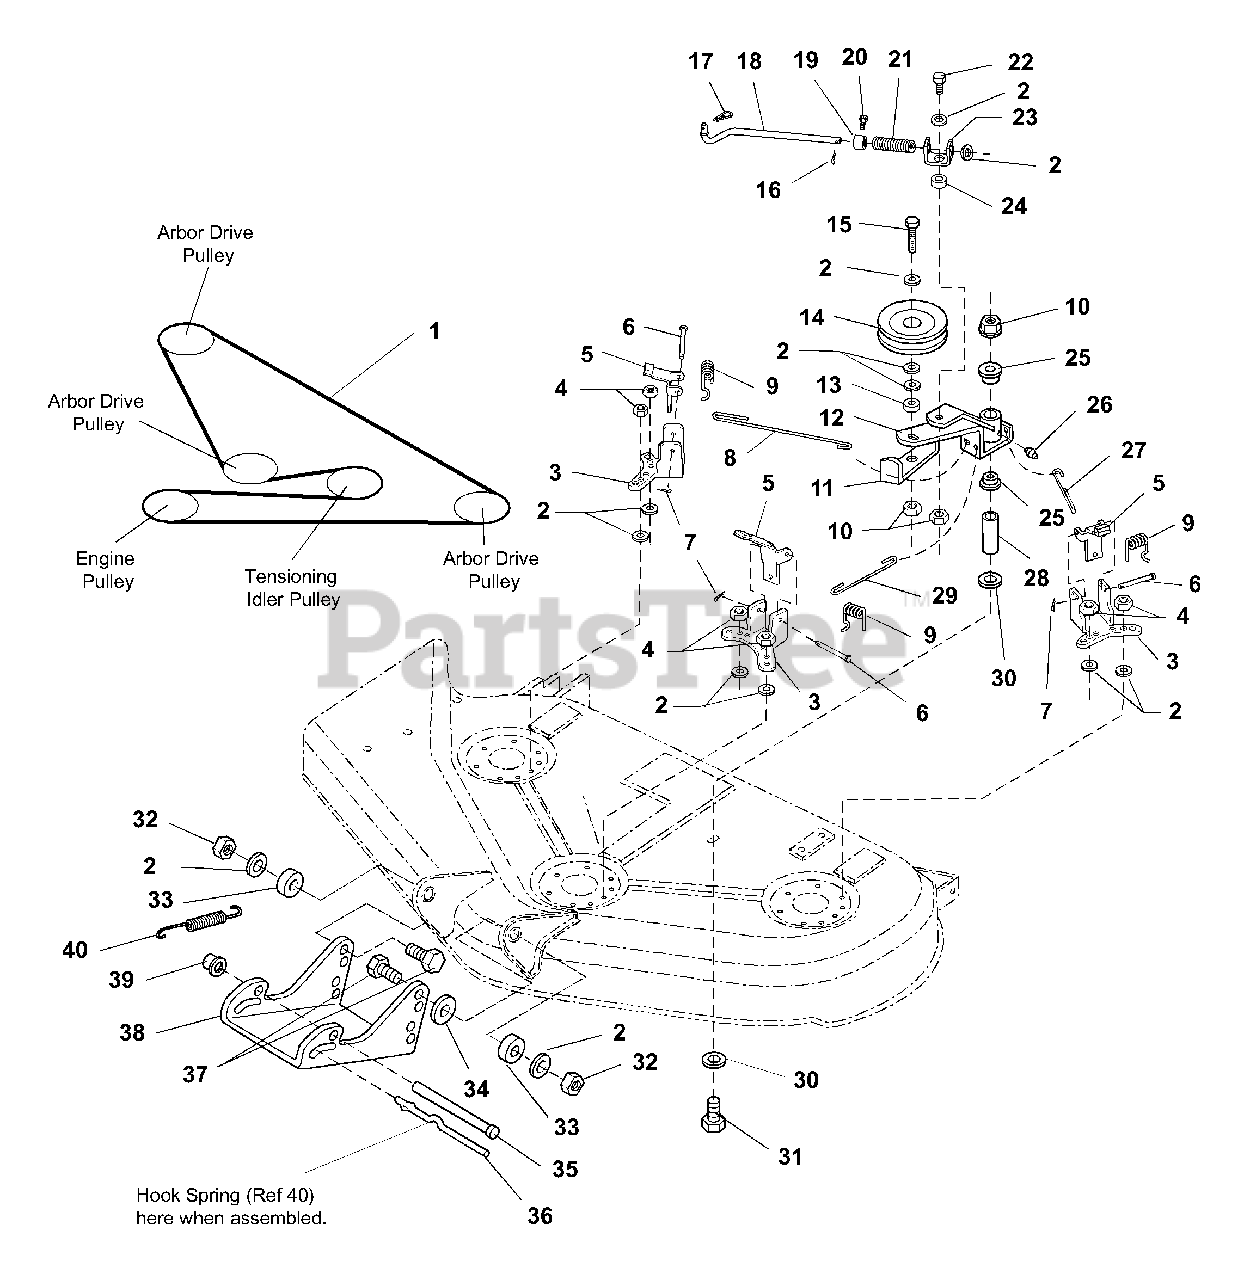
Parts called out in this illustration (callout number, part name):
2	WASHER, 3/8
3	SUPPORT, Brake Actuator
4	NUT, Hex Flange Whix Lock, 5/16
5	ACTUATOR & PAD ASSEMBLY, Brake
6	PIN, Clevis, 3/4 Hd
7	COTTER PIN
8	ROD, Brake R.H.
10	NUT, Hex Flange Whix Lock, 3/8
11	RETAINER, Belt
12	IDLER ARM ASSEMBLY, with Bushings
14	PULLEY ASSEMBLY, Idler
15	CAPSCREW, Hex Hd, 3/8-16 x 2
17	CLIP, Hair Pin
18	ROD, 2 Bends
19	COLLAR, Set
20	SET SCREW, Square Hd Cup Point, 5/16-18 x 1/2
22	CAPSCREW, Hex Hd, 3/8-16 x 1
27	ROD, Brake L.H.
29	ROD, Brake Center
30	WASHER, 3/8
31	CAPSCREW, Hex Hd, 3/8-16 x 2 3/4
32	NUT, Hex Nylon Lock, 3/8-16
34	WASHER, 3/8
35	ROD, Mower Hitch
37	CAPSCREW, Hex Hd, 3/8-16 x 1-3/8
39	NUT, Push, 1/2
40	SPRING
